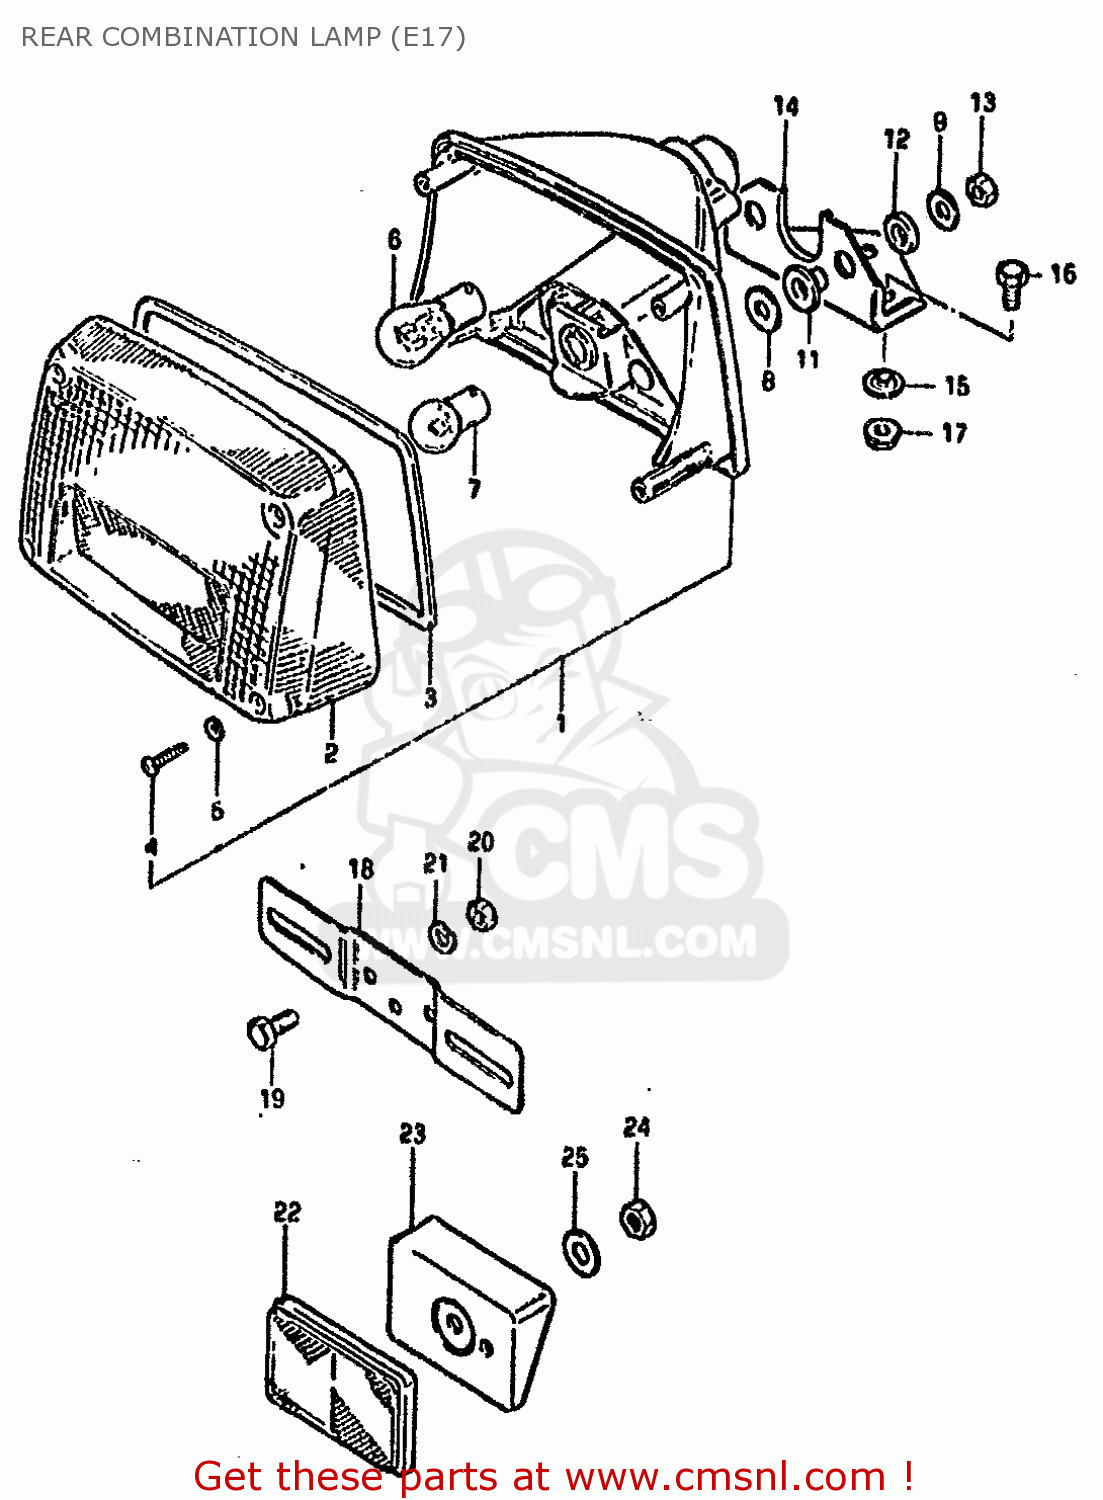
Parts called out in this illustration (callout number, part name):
1	LAMP ASSY, TAIL
2	LENS
3	GASKET (NAS)
4	SCREW,REAR COMBINATION LAMP
5	GASKET (NAS)
6	BULB 12V21/5W
7	BULB
8	WASHER
9	WASHER(6,5X22X1.6)
10	SPACER(6.1X9X7.5)
11	CUSHION
12	CUSHION
13	NUT 6MM
14	BRACKET,RR COMBINATION LAMP
15	WASHER
16	BOLT, UPPER
17	NUT 6MM
18	PLATE,RR LICENSE
19	BOLT
20	NUT
21	LOCK WASHER
22	REFLECTOR,REFLEX
23	SPACER
24	NUT
25	WASHER(5.2X16X1)
